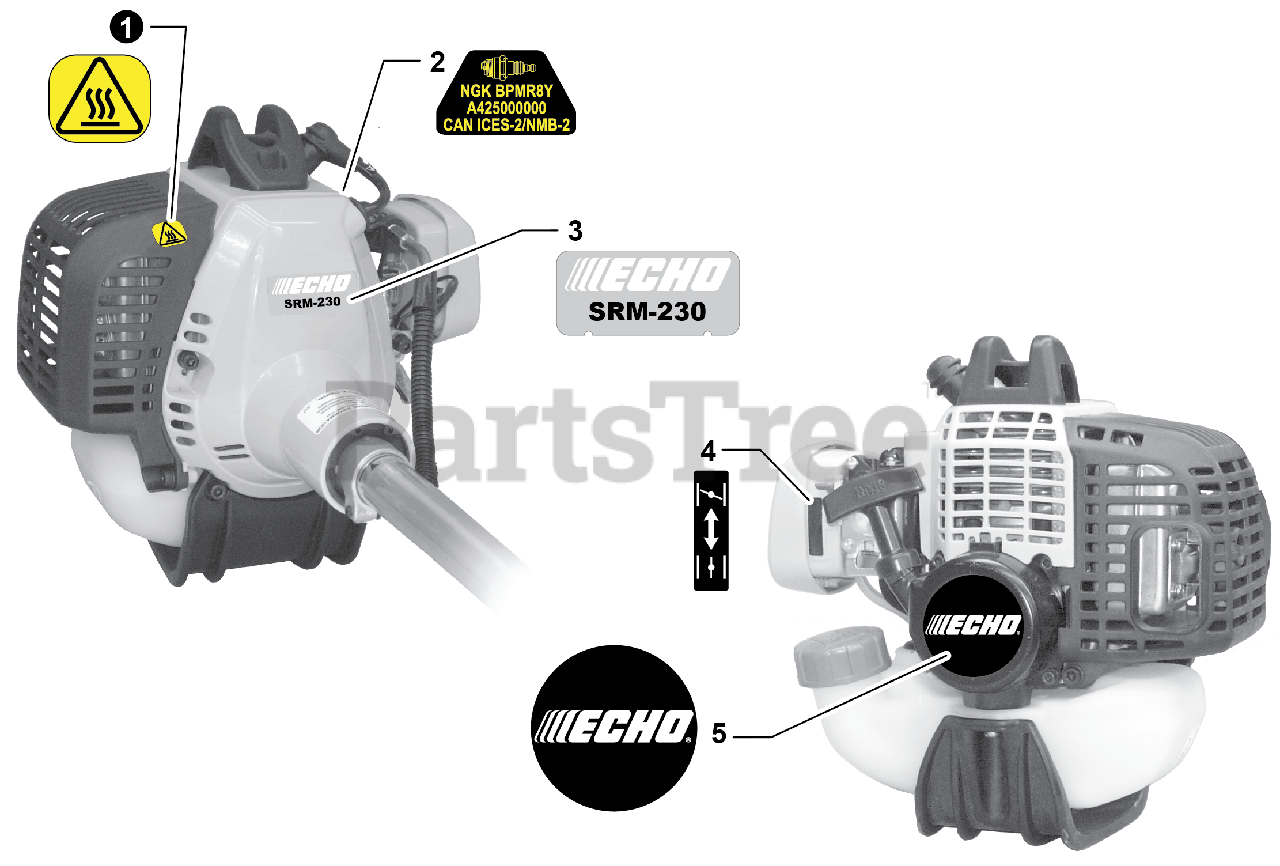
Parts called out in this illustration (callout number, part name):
1	LABEL, CAUTION - HOT
2	LABEL, SPARK PLUG - BPMR8Y
3	LABEL, MODEL - SRM-230
4	LABEL, CHOKE
5	LABEL, RECOIL STARTER
